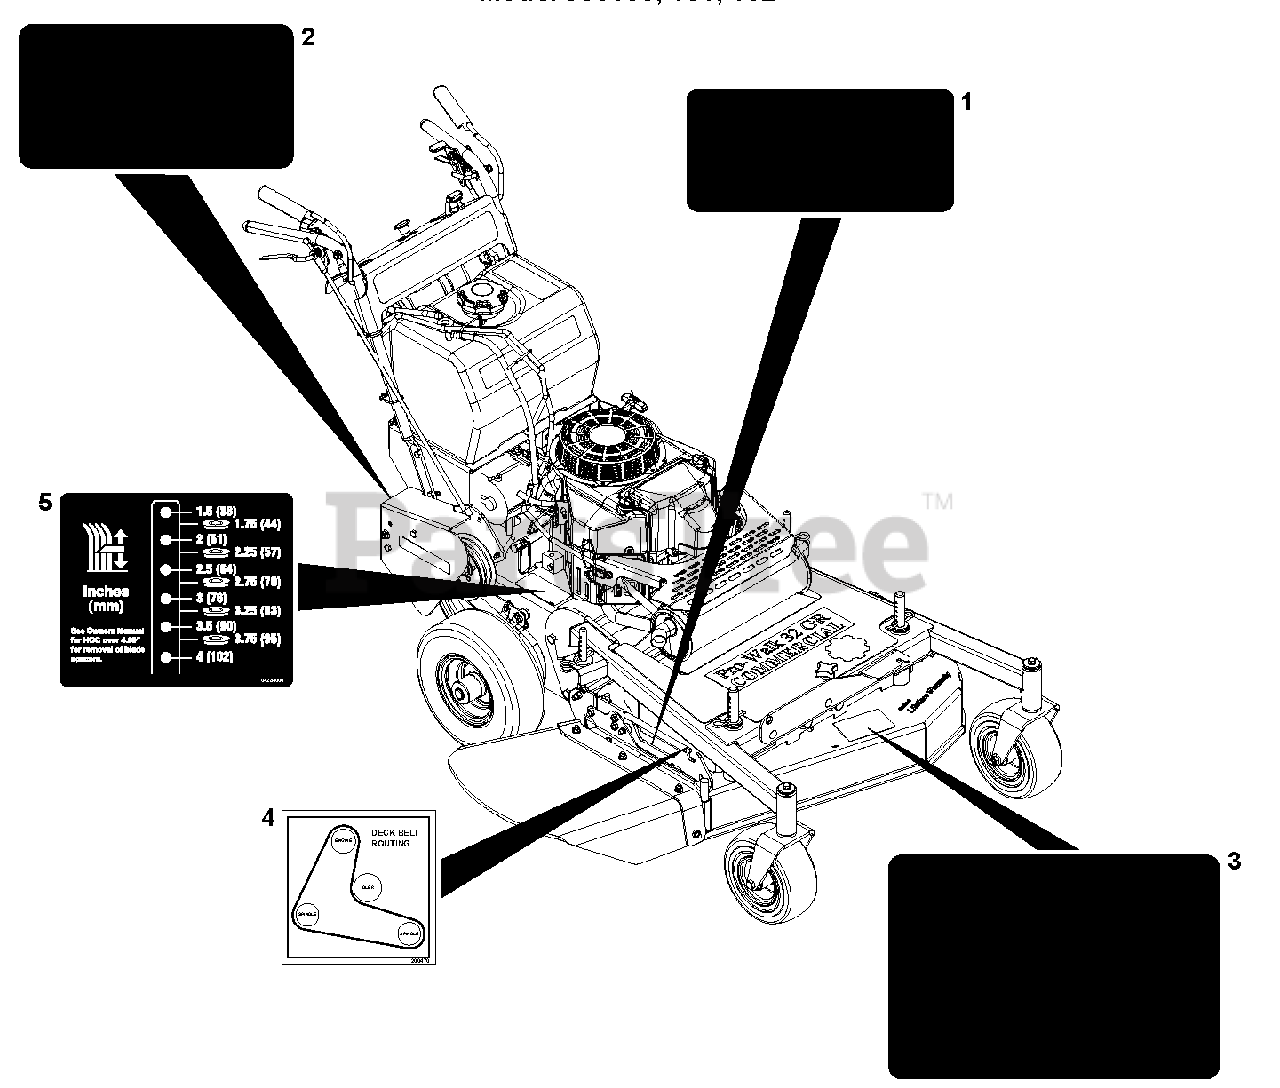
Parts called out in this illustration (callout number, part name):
1	Decal, Warning (SN 000101 – 019999)
2	Decal, Danger-Belt Rotating (SN 000101 – 019999)
3	Decal, Mower Pan Danger (988152) (SN 000101 – 019999)
4	Decal, Deck Belt Routing (988150, 151)
5	Decal, Prowalk Height of Cut (SN 000101 – 019999)
